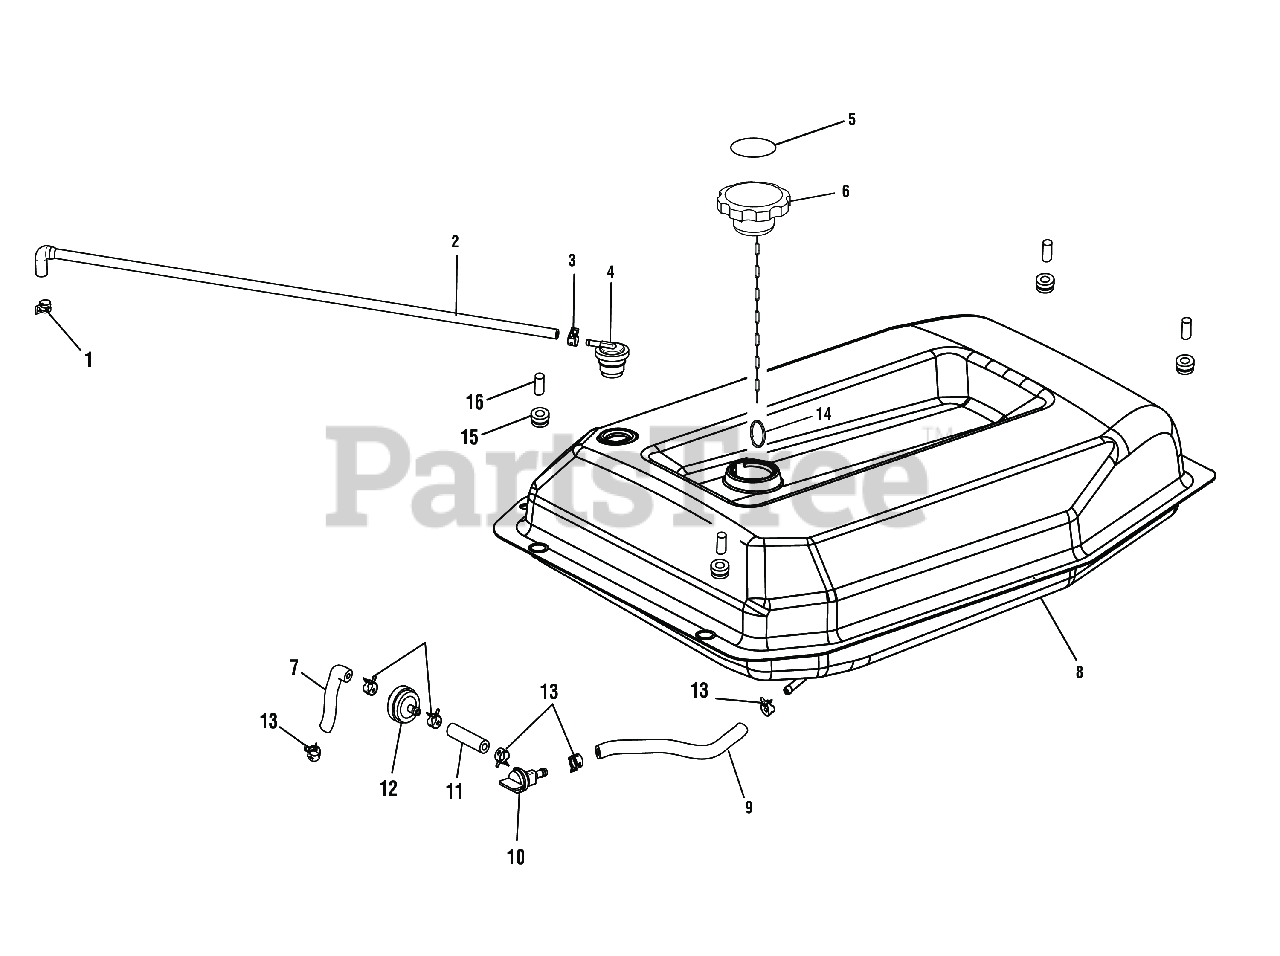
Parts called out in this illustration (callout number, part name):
1	Fuel Line Clamp (10.3 mm)
2	Vapor Hose (590 mm and 30 mm)
3	Vapor Line Clamp (5/16 in.)
4	Fuel Tank Vent Valve (PS905055SA)
5	Remove Cap Fuel Stabilizer Label (English)
6	Fuel Cap Assembly
7	Fuel Hose (185 mm)
8	Fuel Tank
9	Fuel Hose (175 mm)
10	Fuel Shut Off Valve
11	Fuel Hose (55 mm)
12	Fuel Filter Inline (1/4 in.)
13	Fuel Line Clamp (1/2 in.).
14	Ring Clip
15	Bushing (Fuel Tank Isolator)
16	Spacer (Fuel Tank Isolator)
